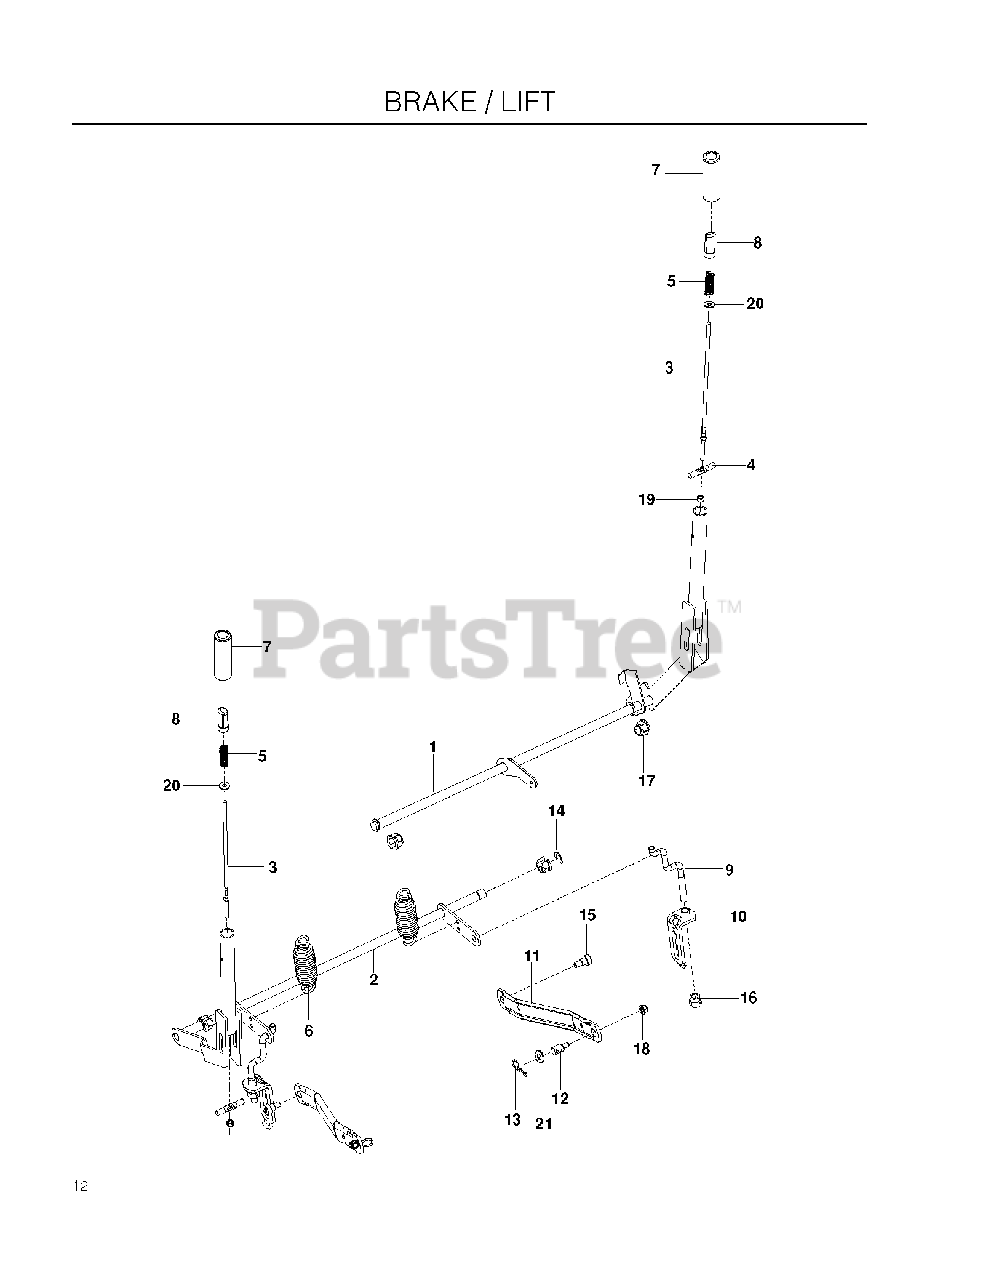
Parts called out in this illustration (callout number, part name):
1	SHAFT.ASSY.BRAKE.WLDMT.BLACK
2	SHAFT, LIFT, BLACK
3	ROD, HANDLE RELEASE
4	RB ROD, LATCH RELEASE
5	SPRING, COMPRESSION
7	GRIP, HANDLE, BLACK 4"
8	BUTTON, PUSH, BLACK
9	LINK, REAR SUSPENSION
10	ASSEMBLY, BRKT LINK
11	ARM.SUSPENSION.MOWER
12	STUD.FASTNER.W/ANTI-ROTATE
13	HAIRPIN #4
14	E-RING 5/8
15	SB 3/8-16 X 3/8 SKT HD ZD
16	NUT, LIFT LINK 7/16-20
17	PLASTIC NUT
18	5/16-18 NYLOC FLANGE NUT
19	RP_NUT 1/4-20 NYLOC
20	WASHER 1/4 FLAT
21	WASHER 5/8 FLAT
